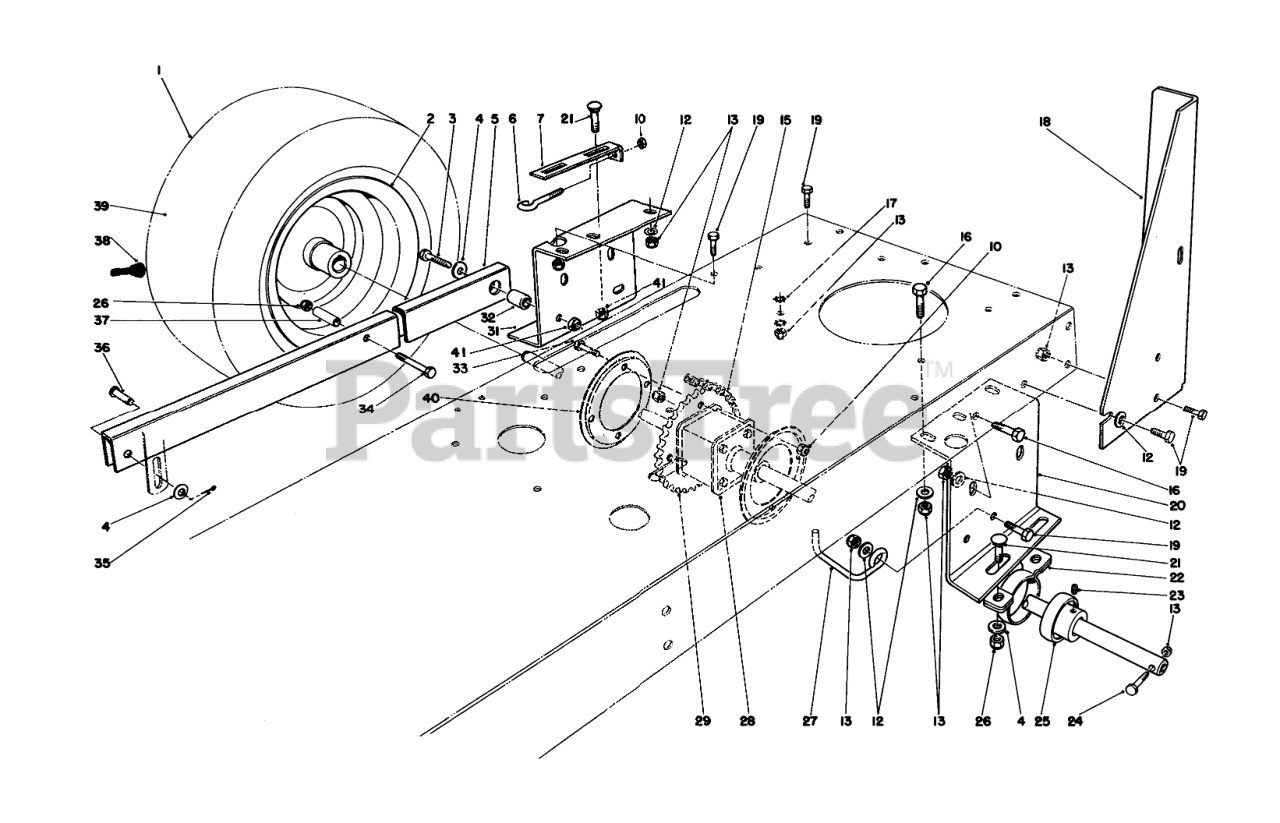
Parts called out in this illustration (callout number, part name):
3	SCREW-HH
4	WASHER-FLAT
5	Arm-Suspension R.H.
6	SCREW-ADJUSTING
7	PLATE-ADJUSTING
10	NUT-HEX
12	WASHER-PLAIN
13	NUT-LOCK, NI
15	ROLLER CHAIN
16	SCREW-HH
17	WASHER-LOCK, INTERNAL
18	LH STANDBAR B
19	SCREW-HH
20	LH REAR AXLE SUPT R
21	BOLT-CARR
22	RTNR-PILLOW BLK
23	SCREW-SET, HSH
24	AXLE MTG BOLT
25	Bearing-Ball (Incl. Ref. #23)
26	NUT-LOCK, NI
27	BELT GUIDE
28	DIFFERENTIAL
29	SPROCKET
31	RH AXLE SUPPORT R
32	PIN-SUPT ARM
33	SCREW-HH
34	SCREW-HH
35	PIN-COTTER
36	PIN-CLEVIS
37	SPACER-SPLIT TUBE
38	STEM-VALVE
39	TUBE-INNER
40	Guide-Chain
41	NUT-LOCK, NI
